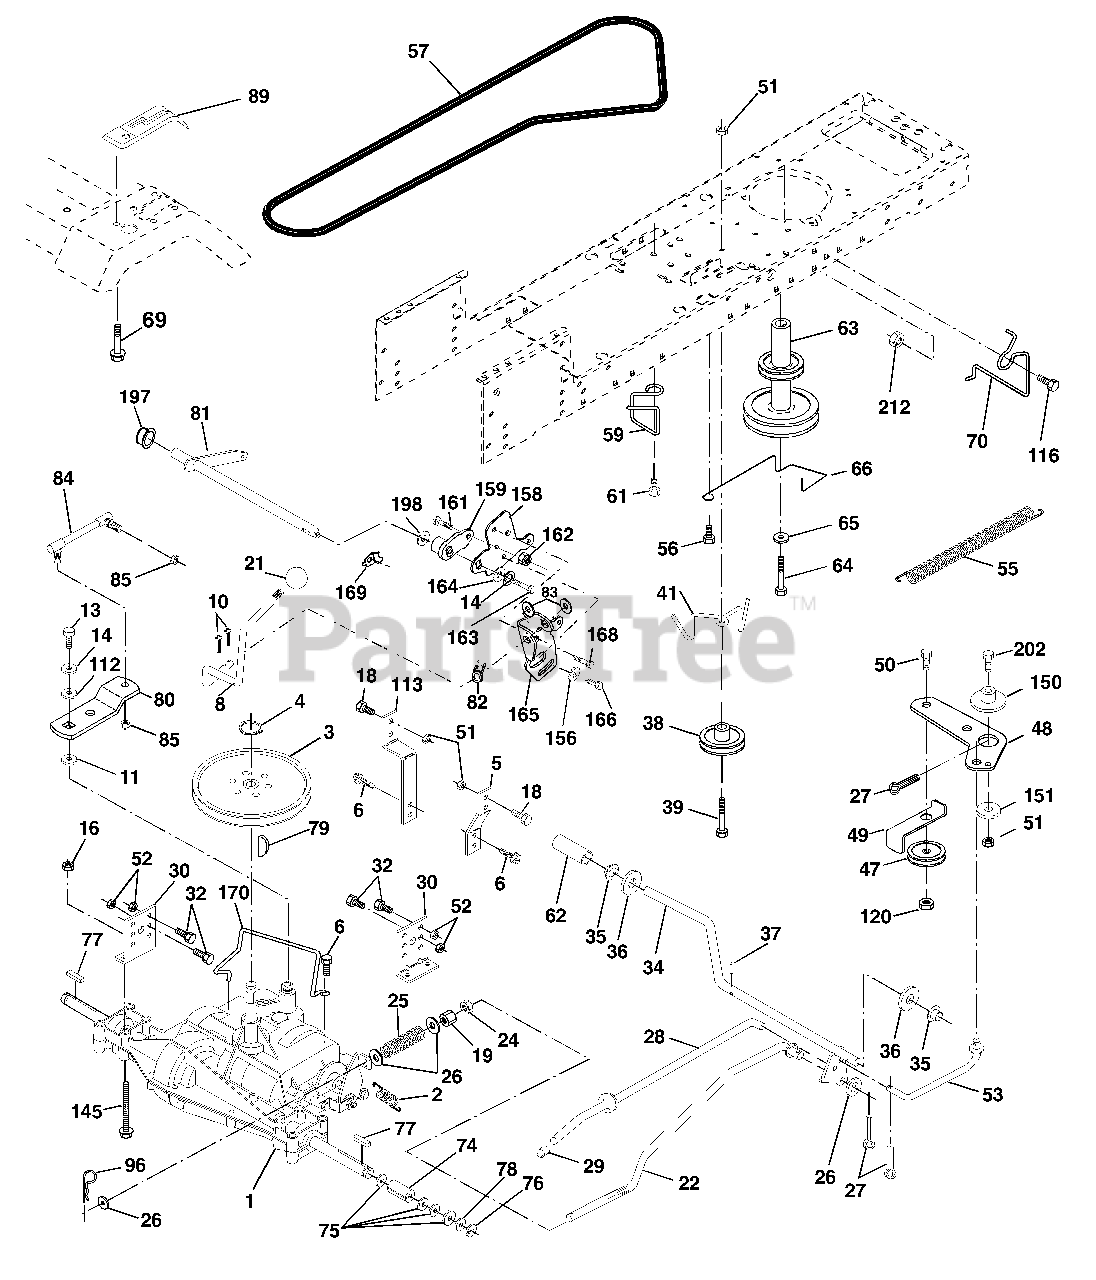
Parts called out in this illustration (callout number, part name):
2	Spring Return Brake T/a Zinc
3	Pulley Transaxle 18/20" tires
4	Ring Retainer # 5100-62
5	Strap Torque 30 Degrees
6	Screw 5/16-18 x 3/4
8	Rod Shifter Fender STLT
10	Pin Cotter 1/8 x 1 Cad
11	Washer Plate Shf 388 Sq Hole
13	Bolt 1/4-28unf Gr8 W/Patch
14	Washer Lock Hvy Helical 1/4
16	Nut Lock Hex w/Ins. 5/16-18 Unc
18	Bolt Fin Hex 3/8-16 Unc x 1 Gr 5
19	Nut Lock Hex w/Ins. 38/-16 Unc
21	Knob Deluxe
22	Rod Brake Blk Zinc 26 840
24	Nut Hex Jam 3/8-16 Unc
25	Spring Rod Brake 2 00 Zinc
26	Washer 13/32 x 13/16 x 16 Ga.
27	Pin Cotter 1/8 x 3/4 Cad
28	Rod Brake Parking Lt/Yt
29	Cap Brake Parking
30	Bracket Mtg Transaxle
32	Bolt Hex Hd 5/16-18 Unc x 3/4
34	Shaft Asm Pedal Foot
35	Bearing Nylon Blk 629 Id
36	Washer 21/32 x 1 x 16 Ga
37	Pin Roll 3/16 x 1"
38	Pulley Composite Flat
39	Bolt Fin Hex 3/8-16unc x 3
41	Keeper Belt Idler
47	Pulley Idler
48	Bellcrank Clutch Grnd Drv STL
49	Retainer Belt Style Spring
50	Bolt Hex Hd 3/8-16 Unc x 1-1/2
51	Nut Crownlock 3/8-16 UNC
52	Nut Crown Lock 5/16-18
53	Link Clutch 7 66
55	Spring Return Clutch 6 75
56	Screw 3/8-16 x 1-1/4
57	V-Belt Gd Drive
59	Keeper Belt Centerspan
61	Screw 3/8-16 x .875
62	Cover Pedal Blk Round
63	Pulley Eng
64	Bolt Hex 7/16-20 x 4 Gr 5
65	Washer Lock Hvy Hlcl Spr 7/16
66	Keeper Belt Engine
69	Screw Hex Wsh Hi-Lo 1/4-1/2 Unc
70	Guide Belt Mower Drive RH
74	Spacer Split
75	Washer 25/32 x 1 1/4 x 16 Ga
76	E-ring #5133-75
77	Key Square
78	Washer 25/32 x 1-5/8 x 16ga
79	Key Woodruff
80	Arm, Shift
81	Shaft Assembly
82	Spring, Torsion
83	Washer 17/32 x 3/4 x 16 Gauge
84	Link Transaxle
85	Nut, Nylock
89	Console, Shift, STLT
96	Retainer Spring
112	Washer 9/32 x 3/4 x 10 Ga
113	Strap Torque
116	Bolt Rd Hd Sqnk 3/8-16 x 1 Unc
120	Nut Lock Flg. 3/8-16 Unc
145	Bolt Hex Flghd 5/16-18 x Gr.5
150	Spacer Retainer
151	Washer 13/32 x 2 x 10 Ga.
156	Washer Srrted 5/16ID x 1 .125
158	Bracket Shift Mount
159	Hub Tapered Flange Shift Lt
161	Bolt Rdhd Sqnk 1/4-20 x 3/4 Gr.5
162	Nut Crownlock 1/4-20 UNC
163	Bolt Hex Fin 1/4-20 UNC x 1 Gr.5
164	Washer 5/8 x .281 x 10 Ga.
165	Bracket Pivot Lever
166	Screw 5/16-18 x 5/8
168	Bolt shoulder 5/16-18 x .561
169	Plate Fastening Lt
170	Keeper Belt T/A
197	Nyliner Snap-In 5/8" ID
198	Washer Nyl 7/8ID x .105"
202	Bolt Carr Sh 3/8-16 x 1-1/2 Gr.5
212	Nut Hex Flange Lock
